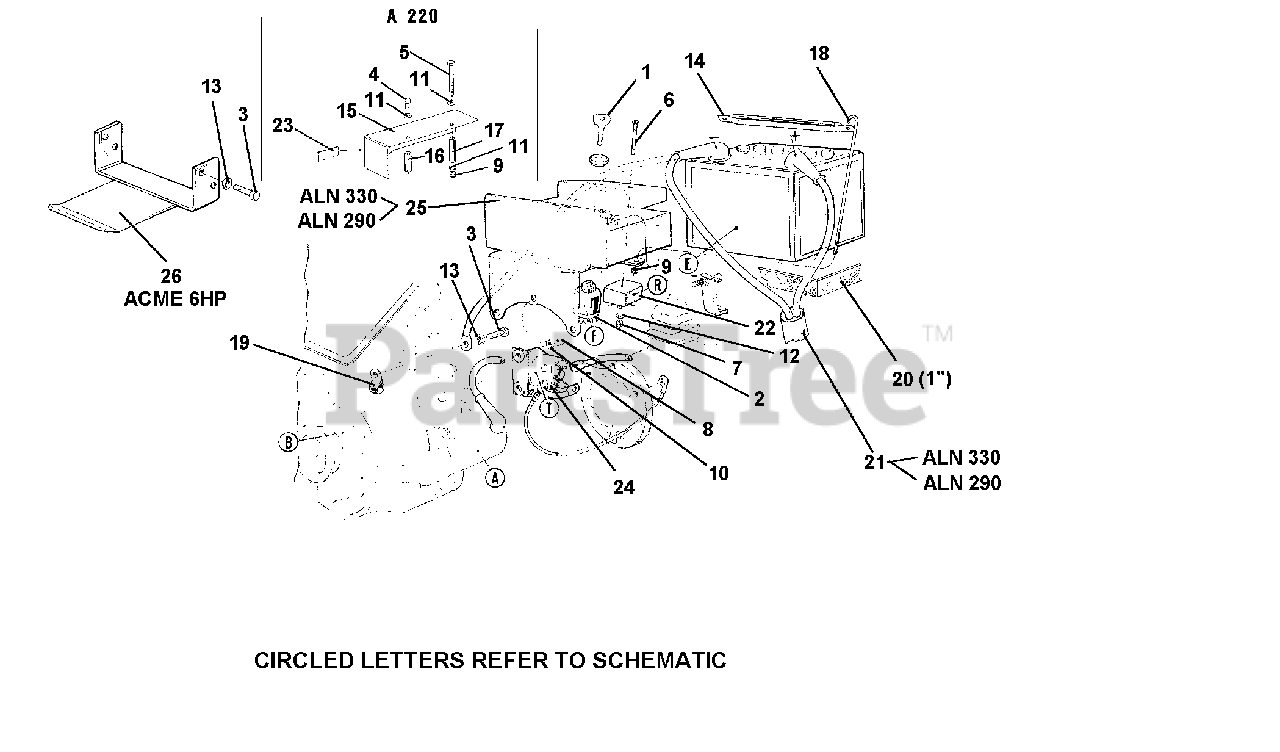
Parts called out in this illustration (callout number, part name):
3	SCREW M8 X 16
4	SCREW M6 X 12
5	SCREW TE M6 X 65
6	SCREW TC M4 X 30 UNI 6107
9	NUT, SELF LOCKING M6
10	WASHER, FLAT 6.4
11	WASHER, LOCK 6.4
12	LOCK WASHER B 4.3
13	WASHER, LOCK 8.4
14	BATTERY BRACKET
15	STOP SWITCH PROTECTION
17	PROTECTION SPACER
18	BATTERY TIEROD
19	SUPPORT, ACCELERATOR CABLE
20	SHOCK-PROOF RUBBER
21	ELEC. START CABLES MC 715
23	CHOKE DECAL
24	BOSCH RELAY 0332002160
25	SUPPORT BATTERY
26	PROTECTION FOR ENGINE A220
